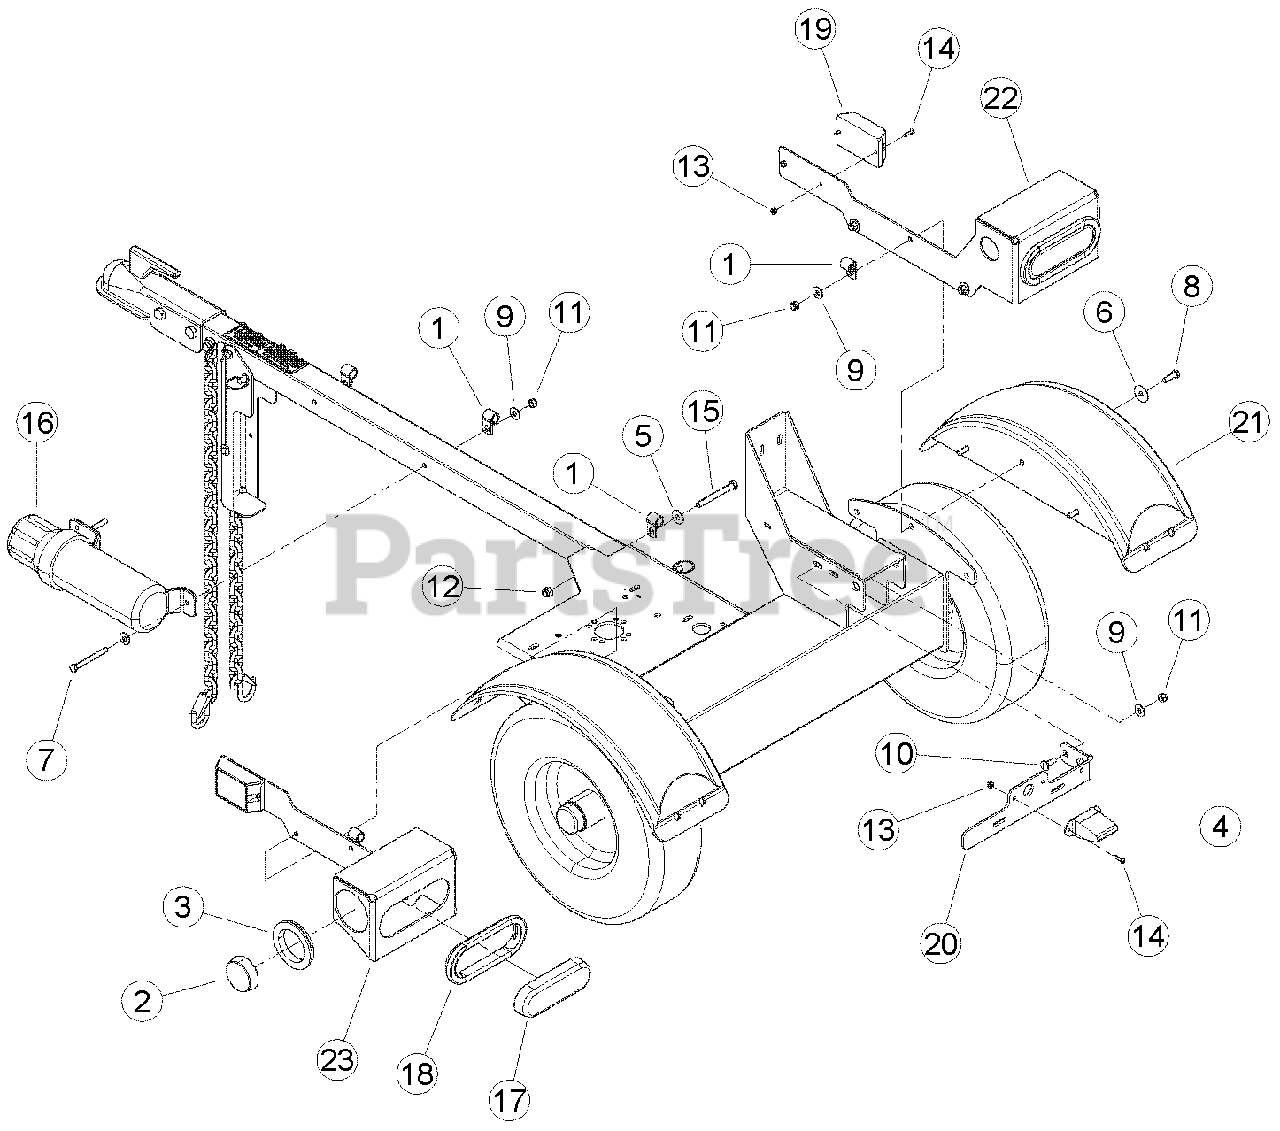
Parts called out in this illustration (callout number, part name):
1	CLAMP, 9/16" COATED
2	LIGHT, RED CLEARANCE
3	GROMMET, CLEARANCE LIGHT
4	LIGHT, LICENSE PLATE
5	WASHER, 3/8 FLAT ZP
6	WASHER, 5/16 FENDER ZP
7	BOLT, 5/16 X 3 HEX GR5 ZP
8	BOLT, 5/16 X 1 HEX GR5 ZP
9	WASHER, 5/16 FLAT ZP
10	BOLT, 5/16 X 1 CRG GR5 ZP
11	NUT, 5/16 NE NYLOCK ZP
12	NUT, 3/8 NE NYLOCK ZP
13	NUT, 10/24 NYLOCK TYPE NM, ZP
14	MACH. SCREW, #10-24 X 3/4 PAN HD PH ZP
15	BOLT, 3/8 X 3-1/4 HEX GR5 ZP
16	CONTAINER, MANUAL
17	TAIL LIGHT, OVAL LED
18	GROMMET, OVAL TAIL LIGHT
19	LIGHT, AMBER MARKER
20	ANGLE, LICENSE
21	FENDER, BLACK PLASTIC DRILLED
22	BRACKET, RIGHT TAIL LIGHT
23	BRACKET, LEFT TAIL LIGHT
